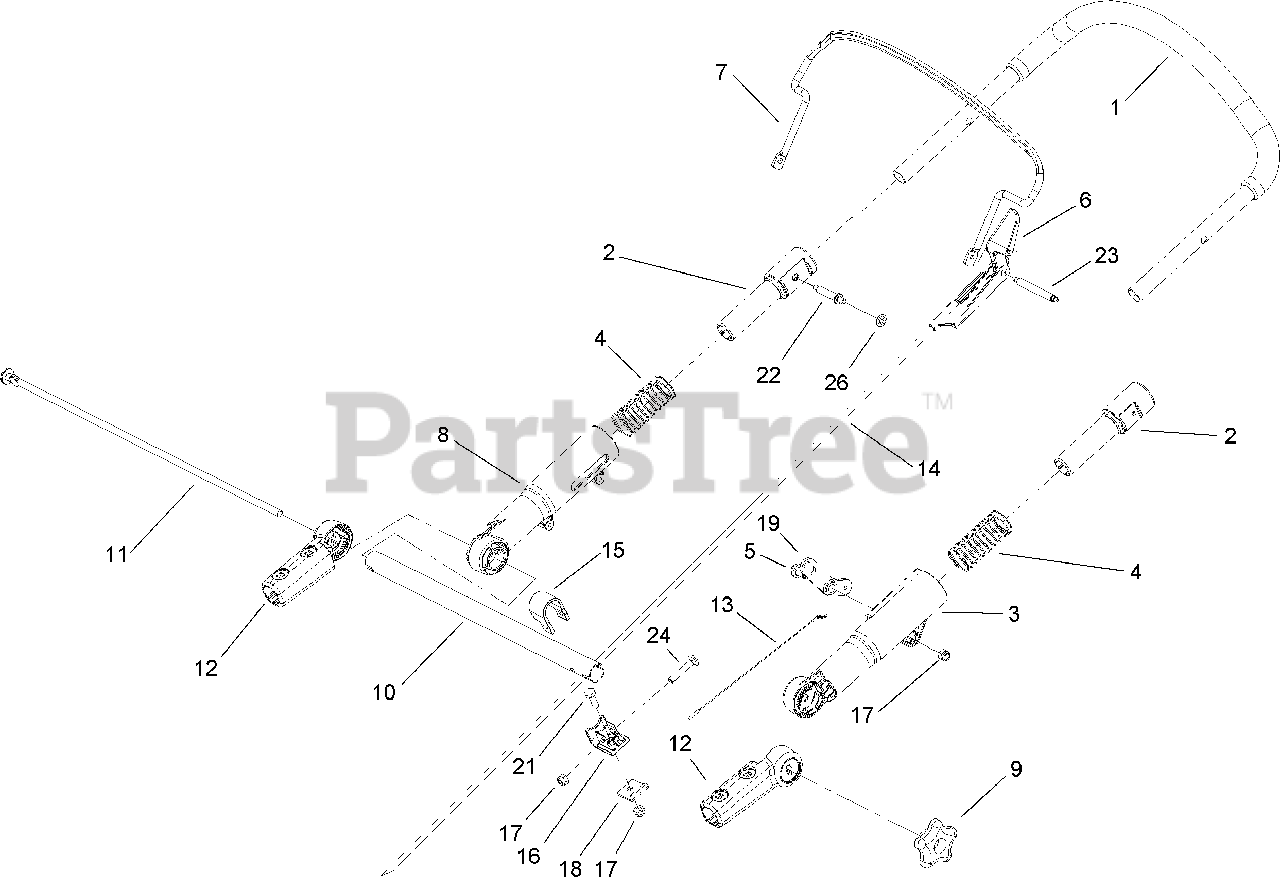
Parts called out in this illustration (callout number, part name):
1	UPPER HANDLE ASM
2	SLEEVE-INNER
3	SLEEVE-OUTER, LH
4	SPRING-COMPRESSION
5	BOLT-SHOULDER
6	STOP-PIVOT
8	SLEEVE-OUTER, RH
11	ROD-THREADED
12	MOUNT-HANDLE, LOWER
13	CABLE-TRACTION
14	CABLE-BRAKE
15	SUPPORT-CABLE
16	SUPPORT-GUIDE, CABLE
17	NUT-LOCK, NI
18	CLAMP-CABLE
19	LEVER-TRACTION
21	SCREW-HH
22	PIN-HANDLE
23	PIN-BAIL, LH
24	SCREW-CARR
26	RETAINER-PUSH ON
